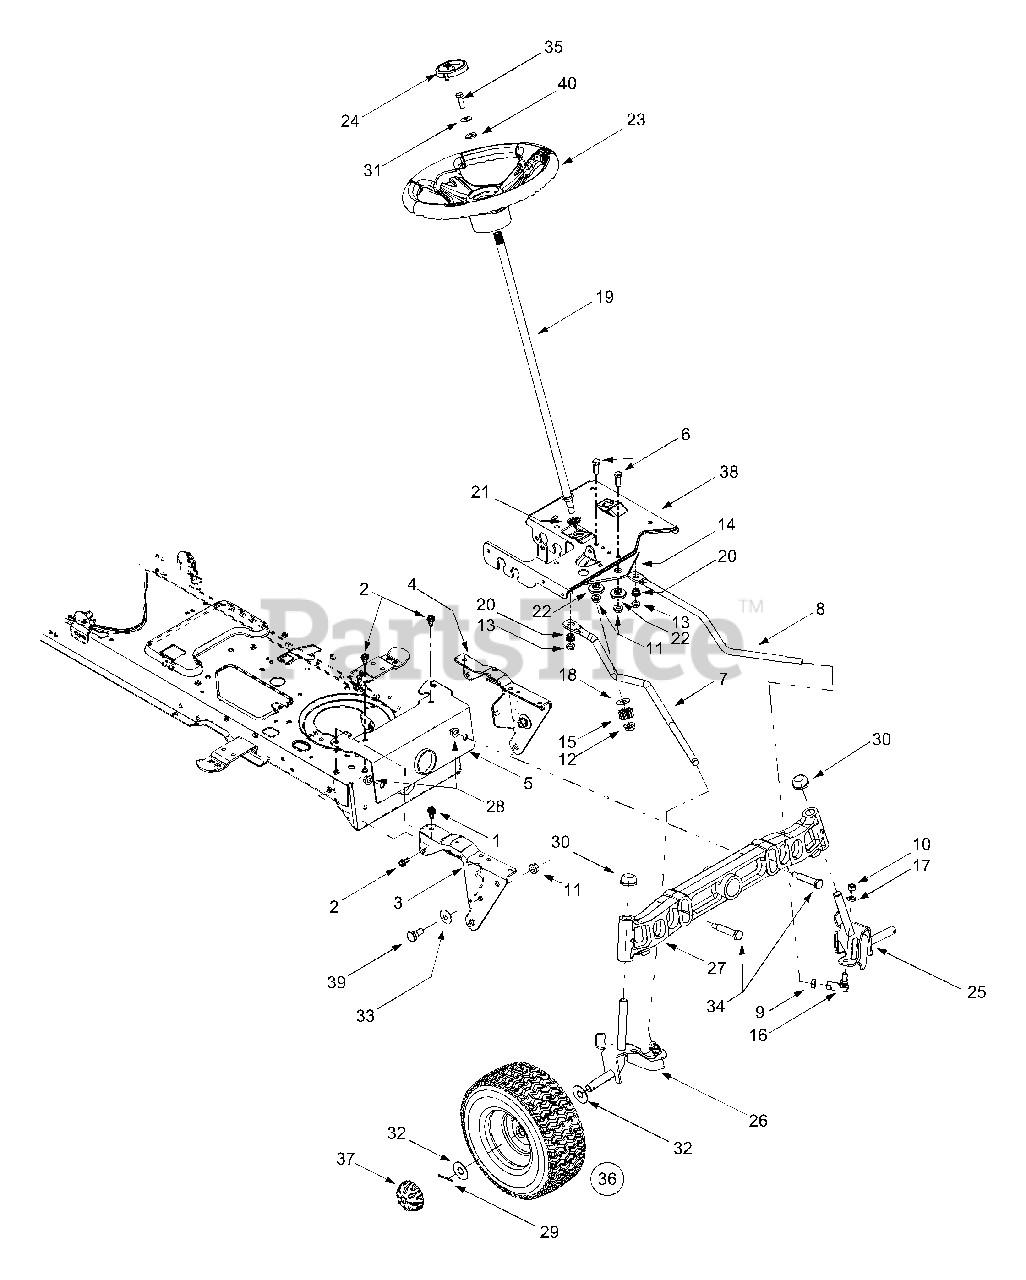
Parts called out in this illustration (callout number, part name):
1	Self-tapping Screw, 5/16-18 x .75
2	Self-tapping Screw, 16-18 x .625
6	Hex Cap Screw, 3/8-16 x 1 (Grade 5)
7	RH Drag Link
8	LH Drag Link
9	Jam Nut, 7/16-20 (Grade 2)
10	Hex Nut, 3/8-24 (Grade 2)
11	Flange Lock Nut, 3/8-16
12	Flange Lock Nut, 7/16-20
13	Flange Lock Nut, 5/16-18
14	Steering Gear, 11/90 Ratio
15	Steering Pinion Gear
16	Ball Joint, 7/16-20
17	Lock Washer, 3/8
18	Flat Washer, .51 x 1.12 x .06
19	Steering Shaft, .625 OD x 24.4
20	Plastic Bushing, .38 ID
21	Hex Flange Bearing, 5/8
22	Shoulder Spacer, .38 ID
23	Steering Wheel, Soft Grip, Three Spoke
24	Steering Wheel Cover
25	LH Axle Assembly, .625 Dia. (Model T604G)
25	LH Axle Assembly .625 / .750 Dia. (Model T604H)
26	RH Axle Assembly, .625 Dia. (Model T604G)
26	RH Axle Assembly .625 / .750 Dia. (Model T604H)
27	Cast Iron Pivot Bar w/ Fittings, ..625 (Model T604G)
27	Cast Iron Pivot Bar w/ Fittings, .75 (Model T604H)
28	Flange Lock Nut, 3/8-16
29	Cotter Pin
30	Push Cap, .625 (Model T604G)
30	Push Cap, .750 (Model T604H)
31	Bell Washer, .34 x .872
32	Flat Washer, .635 x 1.589 x .06
33	Bell Washer, .39 x 1.13 x .062
34	Shoulder Screw, .5 x 2.2, 3/8-16
35	Hex Bolt, 5/16-18 X 1
37	Hub Cap
39	Shoulder Screw, 3/8-16
40	Flat Washer, .406 x .875 x .105
